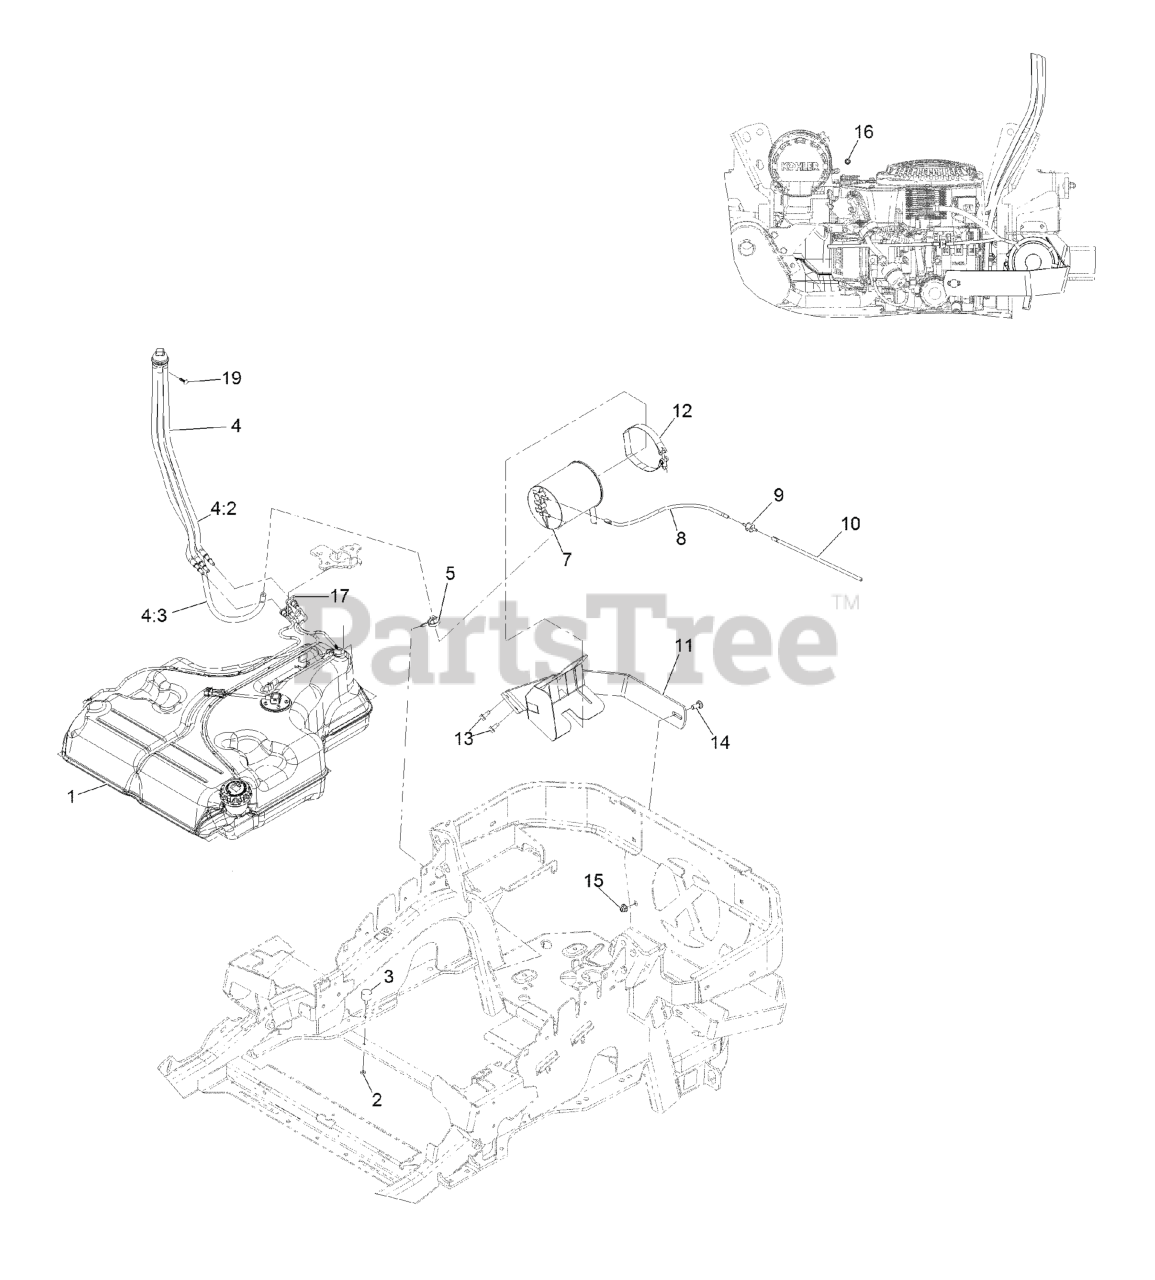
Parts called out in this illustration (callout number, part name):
1	FUEL TANK ASM
2	NUT-JAM
4	FUEL MANIFOLD VENT ASM
4:2	HOSE-FUEL
4:3	HOSE-FUEL
5	CLAMP-HOSE
7	CANISTER-CARBON, 1200CC
8	HOSE-VENT, FORMED
9	VALVE-CHECK, VACUUM
10	HOSE-VENT, FORMED
11	MOUNT-CANISTER
12	CLAMP, T-BOLT
13	Screw-HWH 5/16-18 X 3/4 Tf
14	SCREW-CARR
15	NUT-HF, NI
16	PLUG-PORT
17	RETAINER-LINE, VAPOR
19	PLUG-PLASTIC
